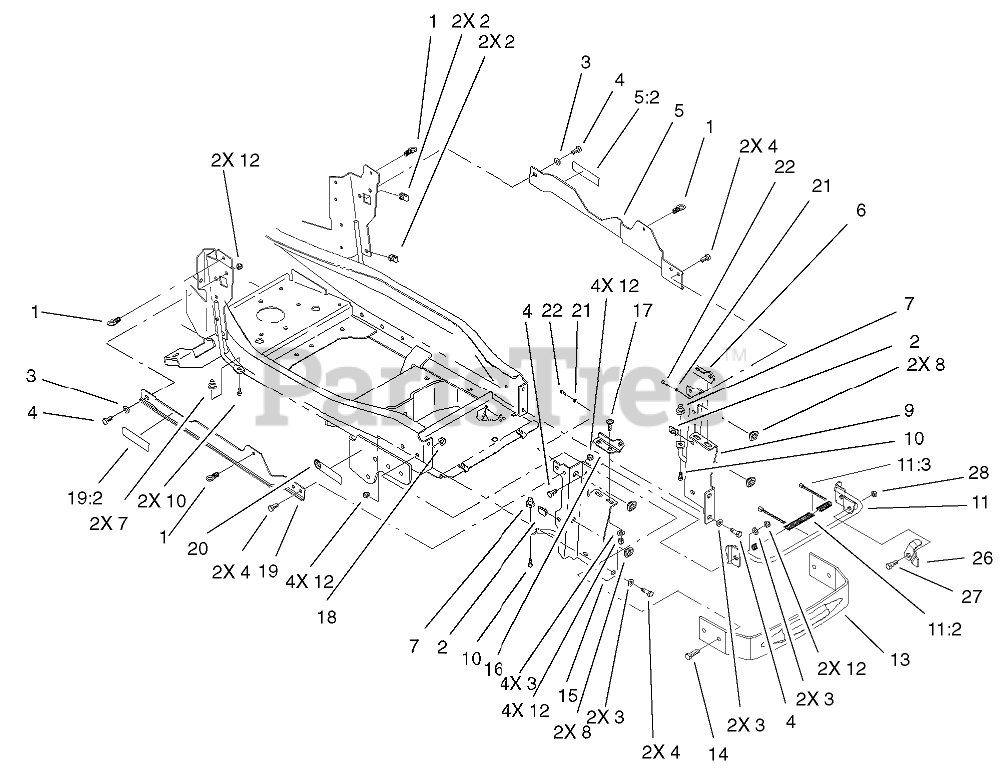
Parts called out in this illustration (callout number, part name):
1	LATCH ASM
3	WASHER-PLAIN
4	SCREW-HH
5	Support ASM (only on: 73580)
5	Support ASM (only on: 73547)
5:2	Decal-Warning (only on: 73547)
5:2	Decal-Warning (only on: 73580)
6	BRACKET-HINGE, LOWER LH
7	MOUNT-SIDEPANEL
8	GROMMET
9	SUPPORT-HOOD, LH
10	SCREW-PLASTITE
11	SUPPORT-HOOD
11:2	COVER-BRACE
11:3	TIE-CABLE
12	NUT-LOCK, NI
13	BUMPER-FRAME
14	SCREW-HH
15	SUPPORT-HOOD, RH
16	BRACKET-HINGE, LOWER RH
17	SCREW-CARR
18	NUT-LOCK, NI
19	Support ASM (only on: 73547)
19	Support ASM (only on: 73580)
19:2	Decal-Warning (only on: 73547)
19:2	Decal-Warning (only on: 73580)
20	DECAL-ATTACH A-MATIC
21	Washer-Flat (only on: 73580)
22	Screw-Selftap (only on: 73580)
26	LEVER-PROP, HOOD
27	BOLT-SHOULDER
28	NUT-LOCK, NI
